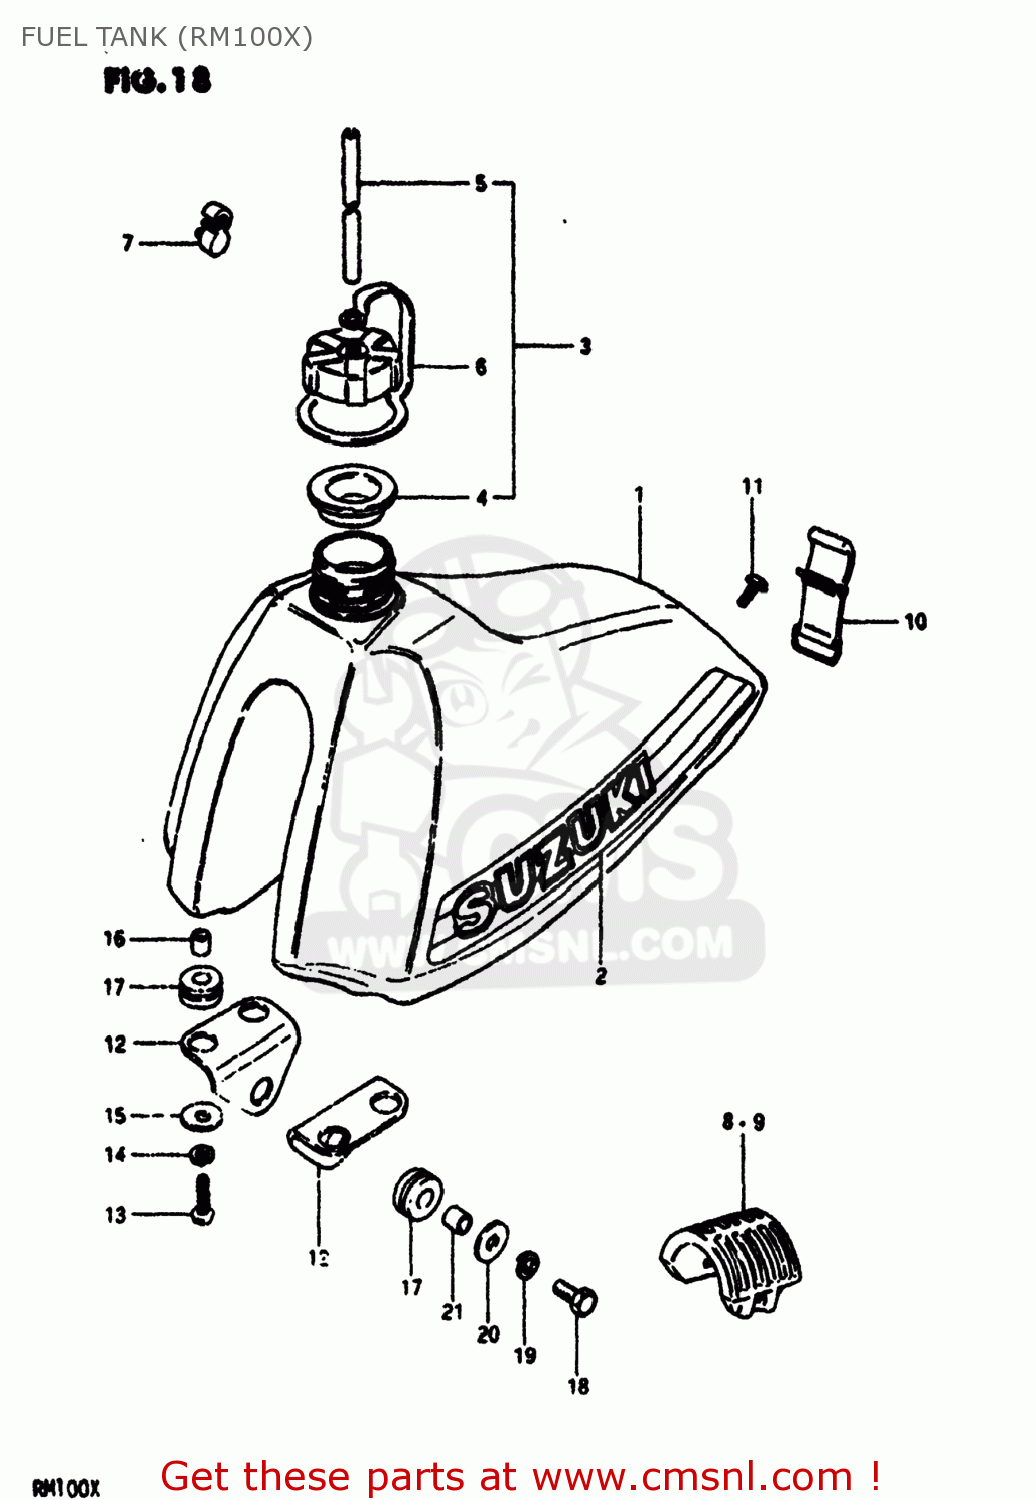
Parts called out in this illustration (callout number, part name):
1	TANK ASSEMBLY,FUEL
2	TAPE SET,FUEL TANK
3	EMBLEM
4	CAP SET,FUEL TANK
5	GASKET,FUEL TANK CAP (NAS)
6	HOSE
7	BAND,FUEL TANK CAP
8	CLAMP,BREATHER HOSE
9	CUSHION,FUEL TANK
10	CUSHION,FUEL TANK
11	BAND
12	SCREW(6X18)
13	BRACKET,FUEL TANK,LOWER
14	SCREW
15	LOCK WASHER
16	WASHER (6.5X24X1.6)
17	SPACER(6.8X12X11)
18	CUSHION
19	BOLT
20	LOCK WASHER
21	WASHER (8.2X24X1.6)
22	SPACER (8.8X12X11)
